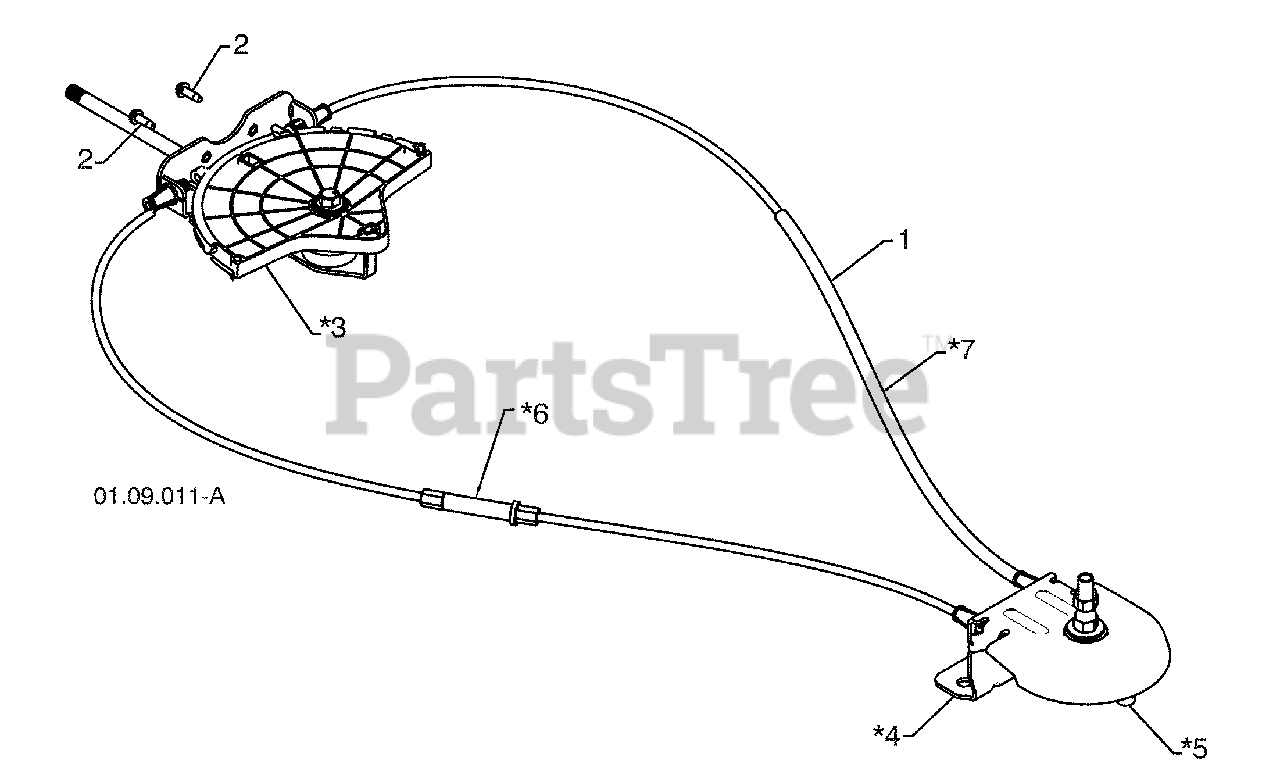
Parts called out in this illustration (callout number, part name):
1	LEVER/CABLE ROTATOR ASSEMBLY
2	SCREW 10-24 X .625
3	ROTATOR HEAD
4	ROTATOR PIVOT BRACKET
5	PULLEY PIVOT
6	CABLE ASSEMBLY ADJUSTABLE GRAY
7	CABLE ASSEMBLY HEAT SHIELD GRAY
